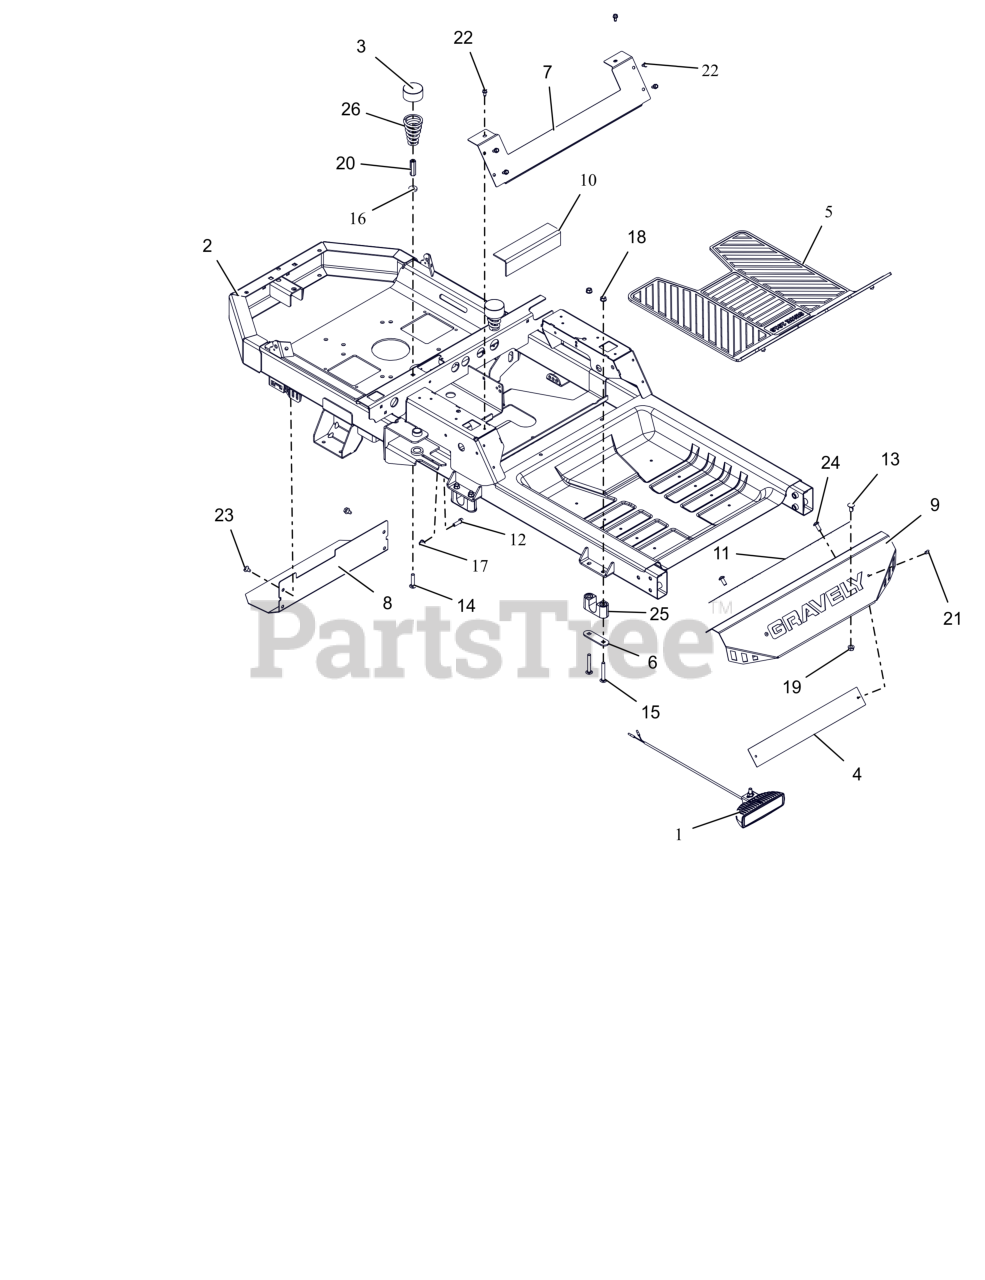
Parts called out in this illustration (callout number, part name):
1	LIGHT, 6 LED W/CON.
2	WLDMT, FRAME IKON XD/ZTX & XL (RED)
4	PLATE, BACK FOOT-REST XL
5	FLOOR MAT, RUBBER - GRAVELY
6	PLATE, BEARING SUPPORT
7	PLATE, SEAT KICK
8	HEAT, SHIELD
9	PLATE, FOOT - GRAVELY
10	PAD, RUBBER-TANK
11	GRIP, FOOT PLATE
12	BLT,HEX .31-18X1.00 G5 ZCC
13	BLT,RHSN .31-18X.75 G5 ZCC
14	BLT,RHSN .31-18X1.50 G5 ZCC
15	BLT, RHSSN.31-18X2.25 G5 ZCC
16	WSHR, FLT .328X.870X.179 ZCC
17	NUT,NYL-FLG .31-18 GF ZCC
18	NUT,LK-CTR-FLG .31-18 GF ZCC
19	NUT-LK-TOP-FLG .312-18 GF ZCC
20	NUT, COUPLING .31-18X1.75 ZCC
21	RIVET, #66 STEEL POP PD BLACK
22	SCR-TAP .25-20X.50 HWH ZCC
23	SCR,TAP .312-18X.50 HWH TR ZCC
24	SCR-RDHDSKTAP .31-18X.75
25	BSHG, DECK LIFT PIVOT
26	SPRING, SEAT
